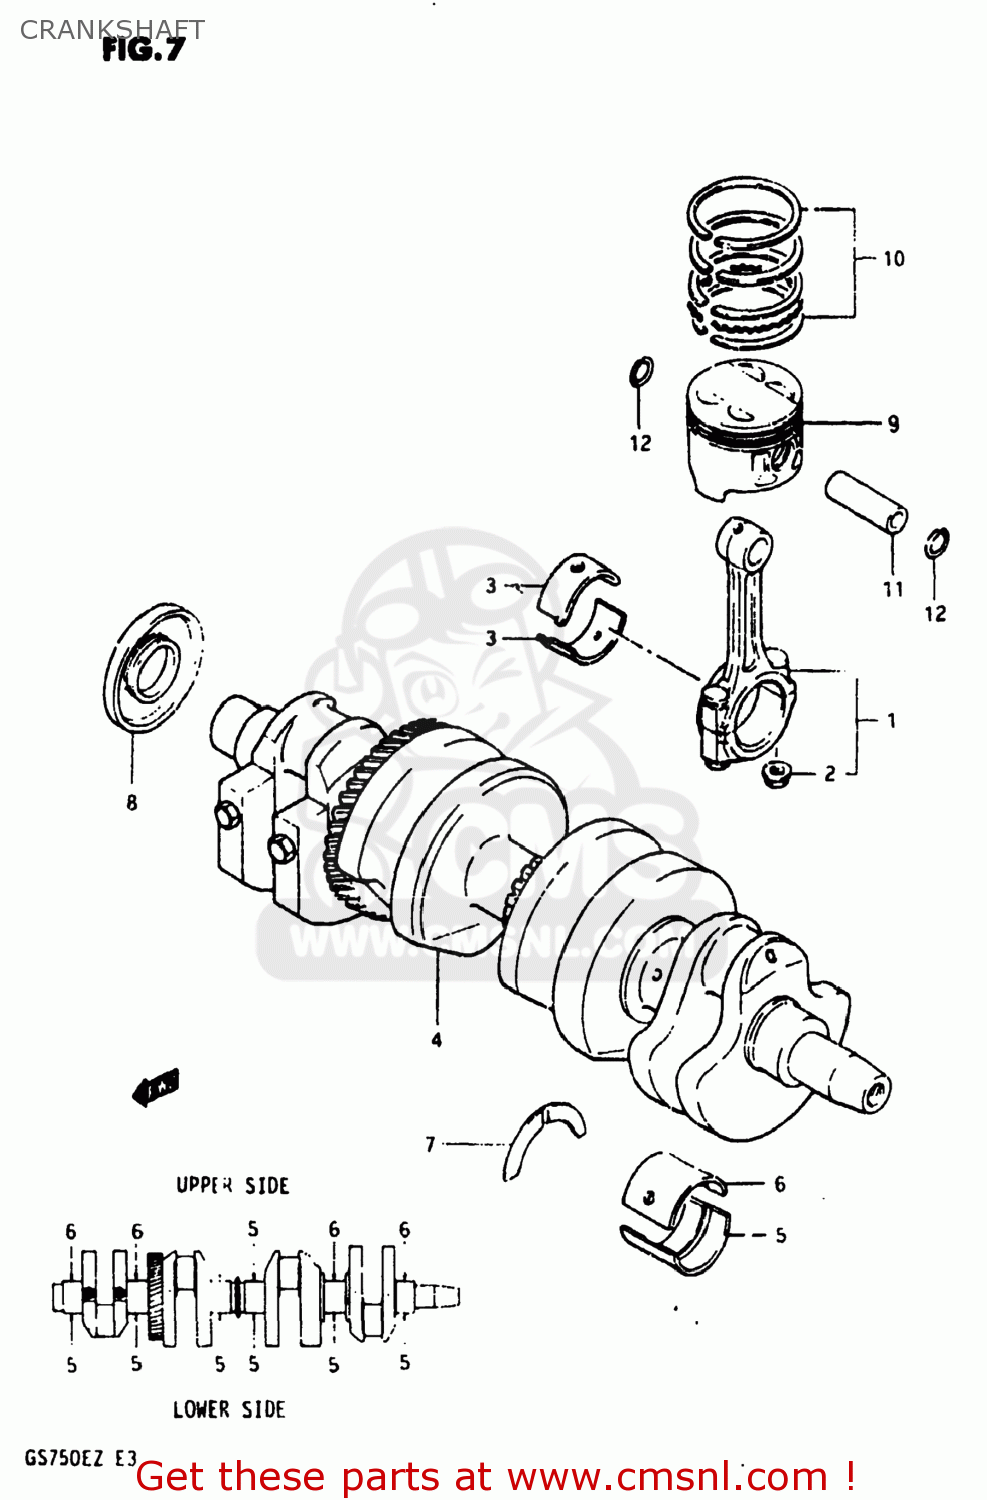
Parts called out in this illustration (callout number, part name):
1	CONNECTING ROD ASSEMBLY
2	NUT
3	BEARING,CRANK PIN
4	CRANKSHAFT
5	METAL CRANKSHAFT
6	METAL CRANKSHAFT
7	PLATE,CRANK THRUST
8	OIL SEAL
9	PISTON
10	RING SET,PISTON
11	PIN,PISTON (18MM)
12	CIRCLIP
